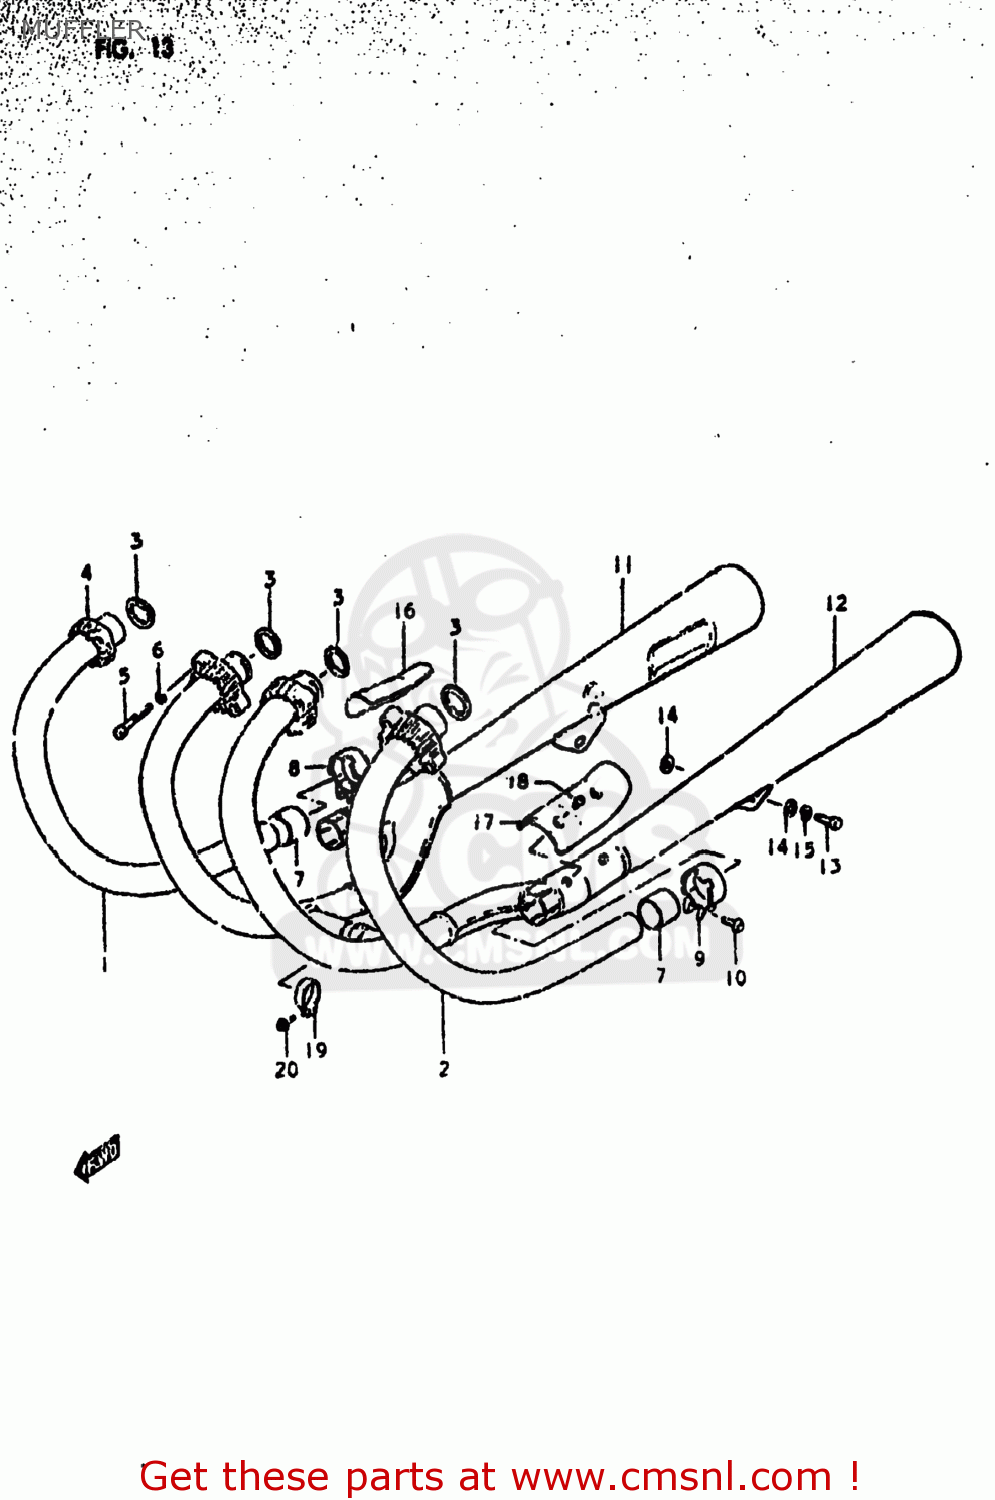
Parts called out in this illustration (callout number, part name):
1	PIPE,EXHAUST,RIGHT
2	PIPE,EXHAUST,LEFT
3	GASKET,EXHAUST PIPE (NAS)
4	CLAMP,EXHAUST PIPE
5	BOLT
6	LOCK WASHER
7	CONNECTOR,MUFFLER
8	CLAMP,MUFFLER CONNECTOR,R
9	CLAMP,MUFFLER CONNECTOR,L
10	BOLT
11	BODY,MUFFLER
12	BODY,MUFFLER
13	BOLT 10X30
14	WASHER
15	LOCK WASHER
16	COVER,MUFFLER,RIGHT
17	COVER,MUFFLER,LEFT
18	SCREW
19	CLAMP,EXHAUST COUPLER
20	BOLT,REAR
